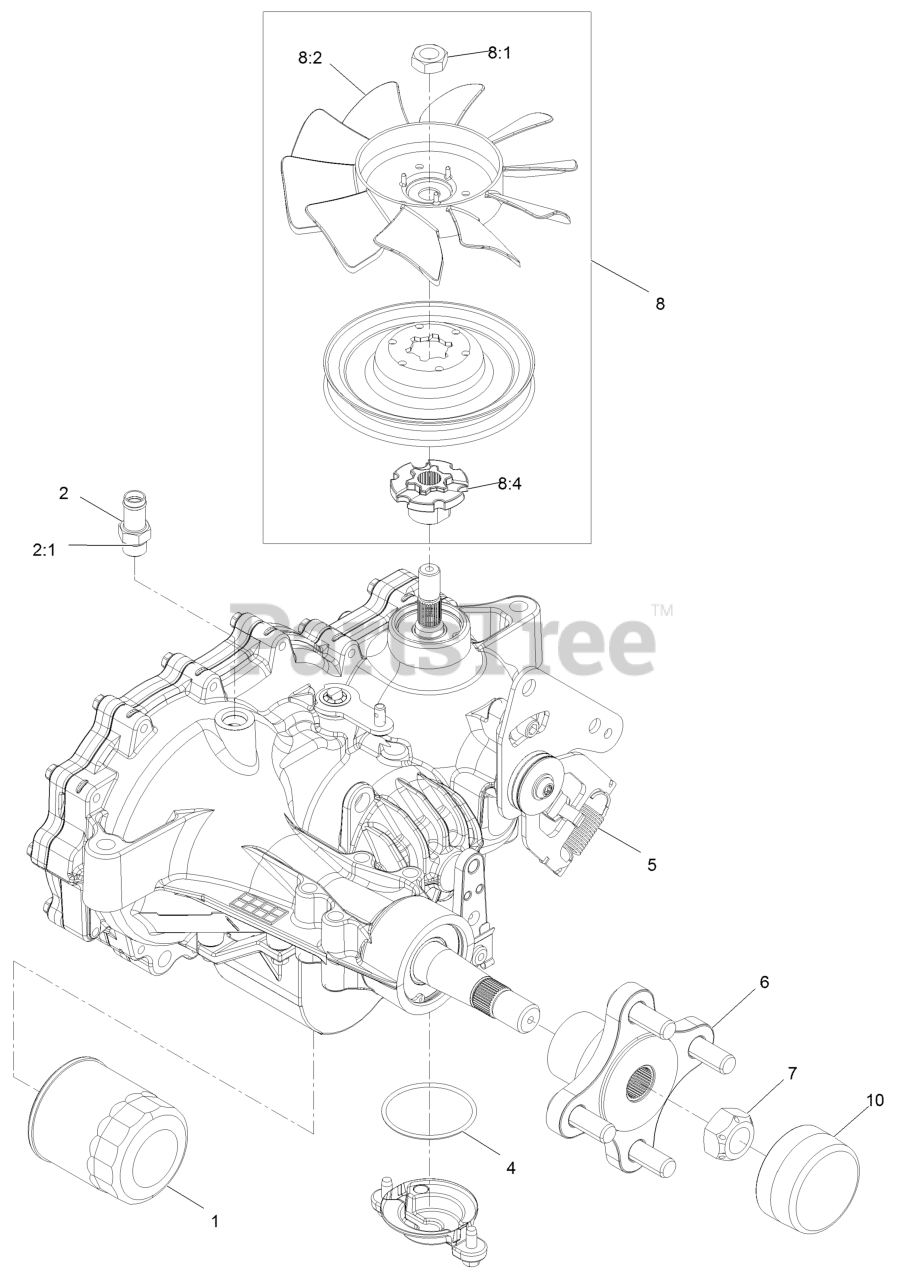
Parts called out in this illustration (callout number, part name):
1	ELEMENT-OIL FILTER, HYD
2	ADAPTER-STRAIGHT
2:1	O-RING
4	O RING-SEAL
5	SPRING-EXTENSION
6	HUB KIT
7	NUT-HUB
8	FAN AND PULLEY KIT
8:4	HUB-PULLEY
10	COVER-NUT, AXLE
